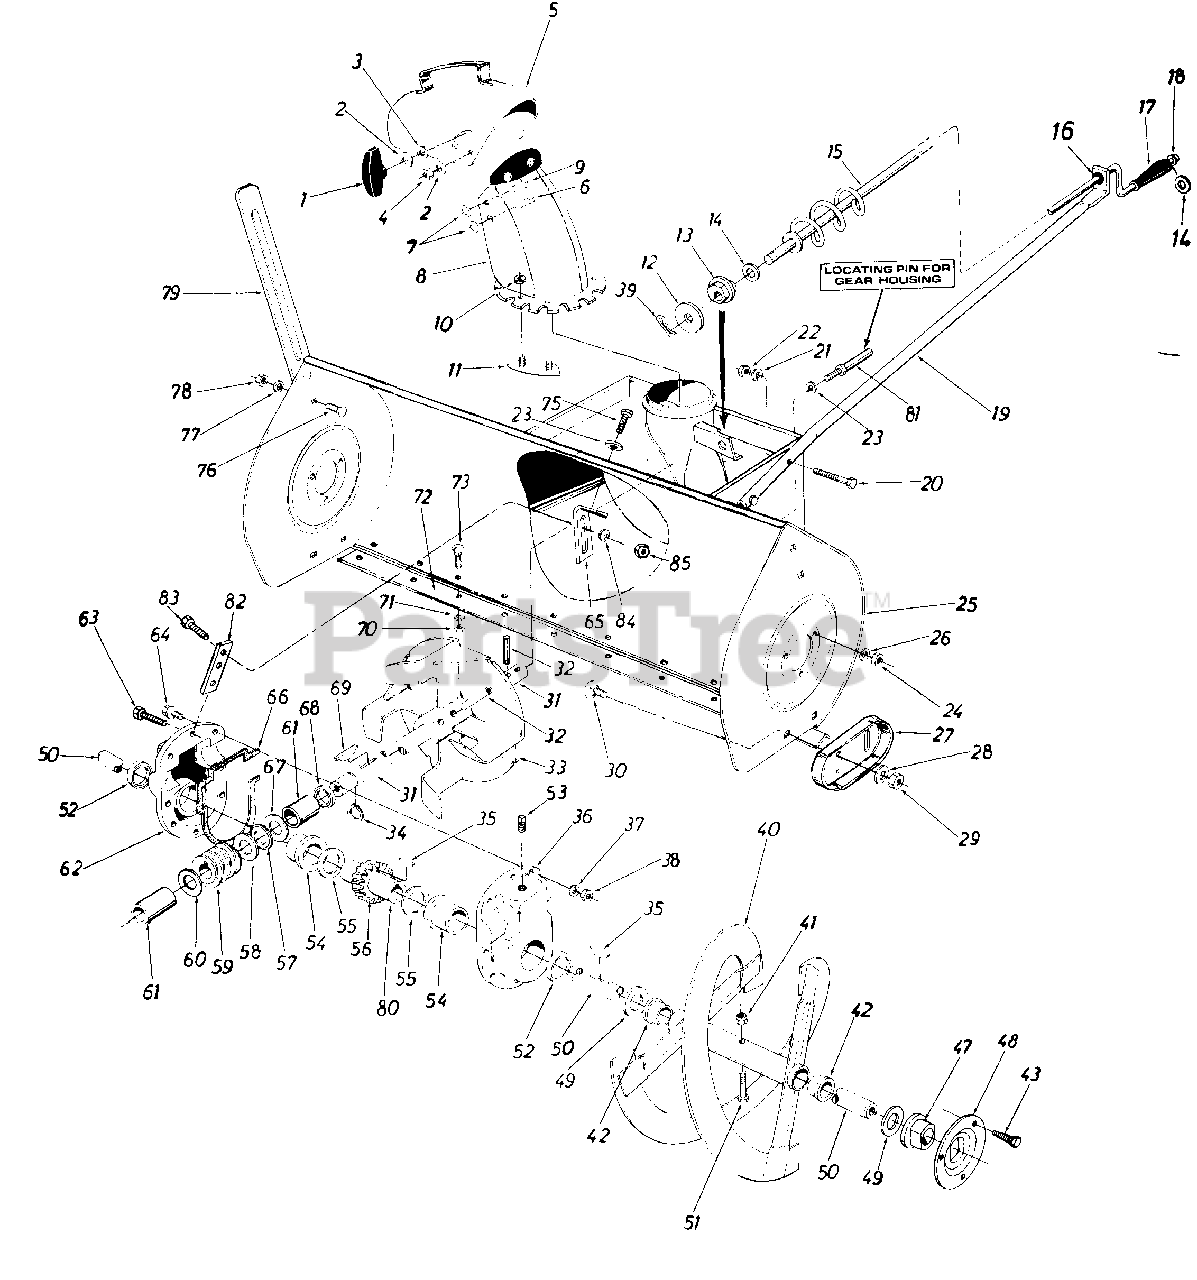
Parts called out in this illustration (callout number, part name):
1	Hand Knob Ass'y.
2	Bell. Wash. .345 I.D. x .88 O.D. x .060
3	Fl.-Wash. .312 I.D. x 1.125 O.D. x .125
4	Hex Cent. L-Nut 5/16-18 Thd.
5	Top Chute Ass'y.
6	Carriage Bolt 5/16-18 x 1.50" Lg.
7	Fl.-Wash. .53 I.D. x 1.25O.D. x .100
8	Chute Ass'y
9	Carriage Bolt 5/16-18 x 1.00"
10	Hex Cent. L-Nut 1/4-20 Thd.
11	Chute Flange Keeper Ass'y.
12	Fl-Wash. .39" I.D. x 1.5" O.D.
13	Hex Bushing
14	Fl-Wash. .385" I.D. x .62" O.D.
15	Chute Crank Ass'y.
16	Grommet
17	Knob Black 3/8" Dia. Hole
18	Push Nut 3/8" rod
19	Chute Crank SupportTubing
20	Hex Scr. 3/8-24 x 1.25" Lg.*
21	L.-Wash. 3/8" Scr.*
22	Hex Ins. Jam L.-Nut 3/8-24 Thd.
23	Bell.-Wash. .345 I.D. x .88O.D. x .060
24	Hex Nut 5/16-18 Thd.
25	Blower Housing Assembly
26	L.-Wash. 5/16" Scr.*
27	Slide Shoe
28	Bell. Wash. .400 I.D. x .88O.D.
29	Hex Nut 3/8-16 Thd.
30	Carriage Bolt 3/8-16 x .75" Lg.
31	Blower Axle
32	Spring Pin Spiral 5/16" Dia. x 1.75" Lg.
33	Blower Fan Ass'y.
34	Snap Ring .875" Dia. Shaft
35	#91 Woodruff Key 1/4" x 3/4" D ia.
36	Gear Housing Half-L.H.
37	Wave Wash. 5/16" I.D.
38	Hex Ins. L.-Nut 5/16-18 Thd.
39	Cotter Pin
41	Hex L-Nut 5/16-18 Thd.
42	Plastic Bushing
43	Hex Sems Scr. 5/16-18 x .75"
47	Flange Bearingw/flats 1.00" I.D,.
48	Bearing Housing
49	Fl-Wash. 1.00" I.D. x 1.75" O. . x . 1 00"
50	Spiral Axle
51	Hex Scr. 5/16-18 x 1.75" Lg.
52	Oil Seal 1.50" I.D.
53	Filler Plug
54	Flange Bearing 1.503 I.D.
55	Fl.-Wash. 1.50" I.D. x 2.0" O.D . x .030
56	Double Threaded Worm Gear L.H.
57	Thrust Bearing .88" I.D. x 1.44" O.D.
58	Fl.-Wash. .88" I.D. x 1.5" O.D. x .030
59	Double Threaded Worm-L.H.
60	Fl.-Wash. . 88 1. D . x 1.4" 0 . D . . 1 55
61	Sleeve
62	Gear Housing Half-R.H.
63	Hex Scr. 5/16-18 x 1.25" Lg.*
64	Hex Scr. 5/16-18 x 1.00" Lg.*
66	Rubber Gasket
67	Fl.-Wash. 88" I.D. x 1.4" O.D. x . 1 55
68	Oil Seal .875" I.D.
69	#9 Hi-Pro Key 3/16" x 3/4" Dia. x .155
70	Hex Nut 5/16-18 Thd.*
71	L.-Wash. 5/16" Scr.*
73	Carriage Bolt 5/16-18 x .75" Lg.*
75	Hex Wash.Hd.Self-Tap5/16-18
76	Carriage Bolt 5/16-18 x .62" Lg.*
77	L.-Wash. 5/16" Scr.*
78	Hex Nut 5/16-18 Thd.
79	Guide Blade
80	Worm GearShaft
81	Stud 3/8-16 x 2.75" Lg.
82	Gear Hsg. Support Plate
83	Hex Bolt 1/4-28 x .75' Lg.
84	Bell.-Wash. .28 I.D. x .75" O.D.
85	Hex Nut 1/4-28 Thd.
